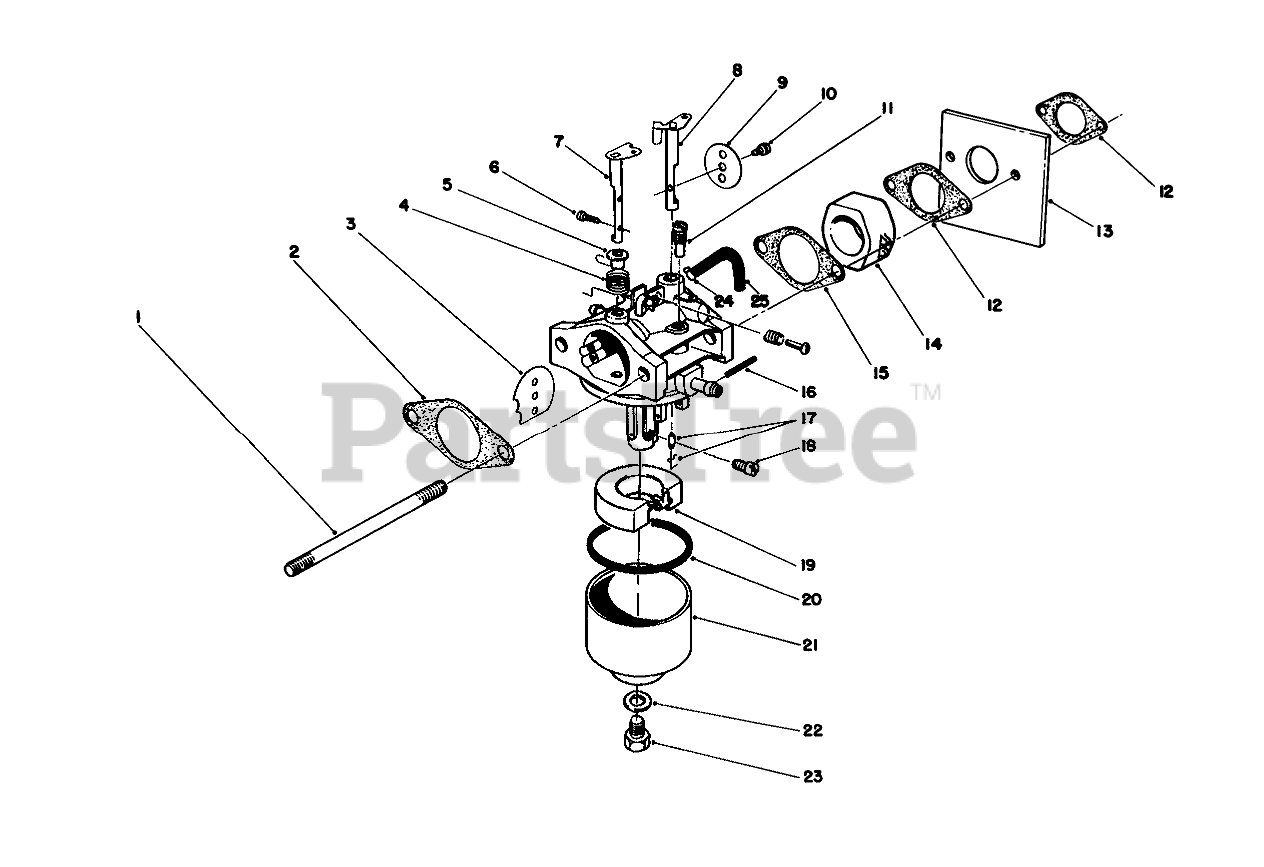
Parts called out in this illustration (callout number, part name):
1	STUD-CARBURETOR
2	GASKET-AIR CLEANER
3	PLATE
4	SPRING
5	BUSHING
6	SCREW
7	SHAFT-CHOKE
8	SHAFT
9	PLATE
10	Screw-Throttle
11	PILOT JET
12	GASKET
13	SHIELD-CARBURETOR
14	INSULATOR-CARBURETOR
15	GASKET-CARB
16	Pin
17	NEEDLE
18	JET-MAIN
19	FLOAT
20	GASKET
21	Bowl-Float
22	GASKET
23	Bolt
24	CLAMP
25	VENT TUBE
